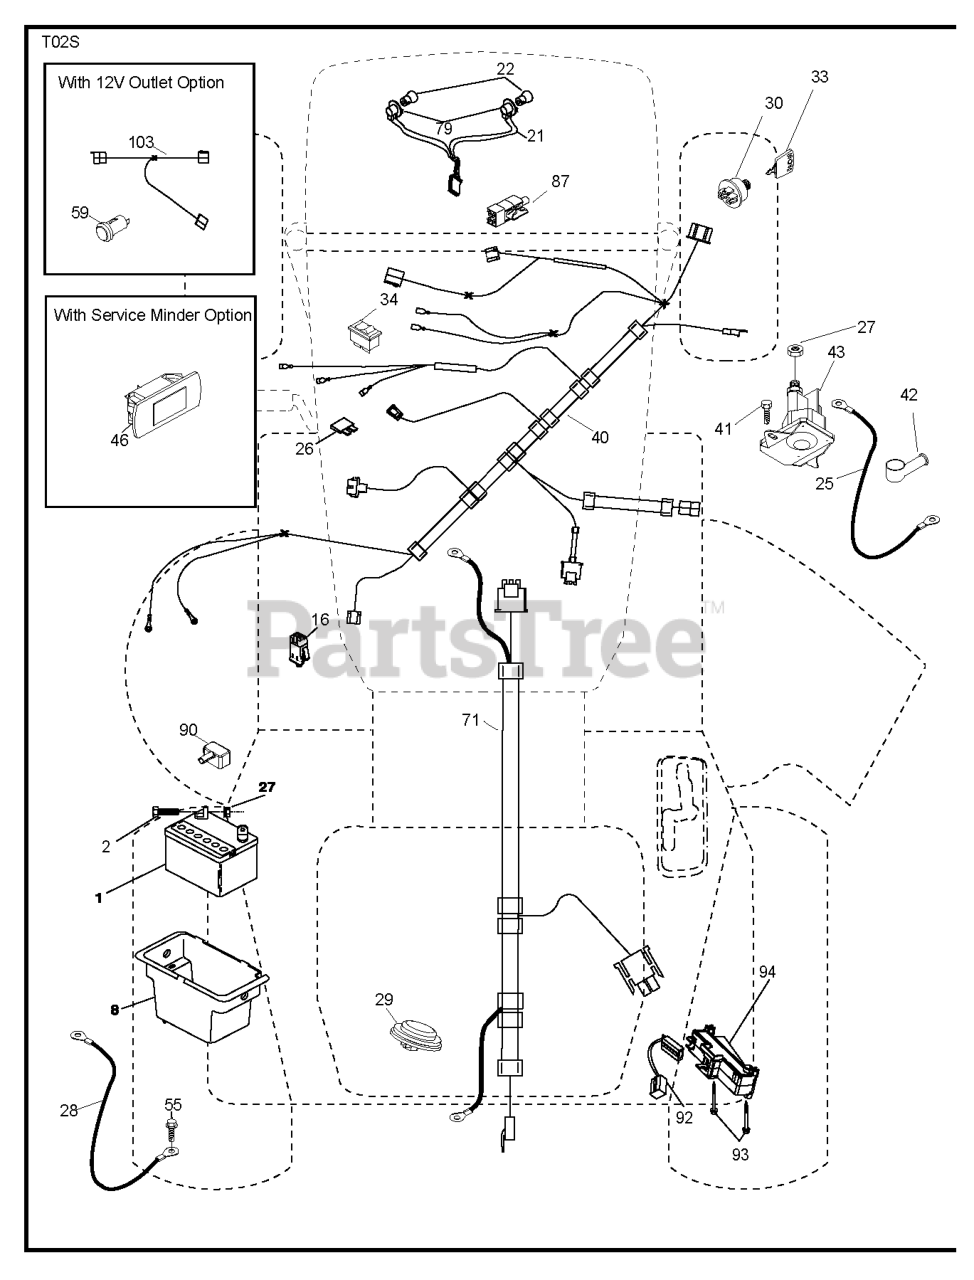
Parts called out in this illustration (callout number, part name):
1	Battery 12 Volt 25 Amp
2	BOLT.HEX.1/4.X.3/4.DICHROMATE
8	BOX.BATTERY.MNT.REAR.L
16	SWITCH INTERLOOK PUSH-IN
21	HARNESS.LIGHT W/4152J BULBS
25	CABLE.STARTER.6GA.BL/RED.14.
26	FUSE 20AMP
27	NUT
28	CABLE.BLACK.18"REAR.BA
29	SWITCH.SEAT.DELTA.OPC.
30	SWITCH.IGN.DELTA.W.LGH.ROS
33	KEY.CHAIN.BLISTER.PACK.GEN.USA
40	HARNESS IGN. DASH
41	SCREW
42	TERMINAL COVER
43	SOLENOID.W/BRASS.PLUNGER
46	RP.GUAGE.SRVCMNDR.HRMTR.
55	SCREW 5/16"
71	HARNESS.IGN.CHASS.TEX.REAR.BAT
79	BULB HOLDER ASM.
87	SWITCH.INTRLCK.CLUTCH.
90	COVER, TERMINAL BATTERY
92	HARNESS.PIGTAIL.CONSLE
93	SCREW.PLASTITE
94	MODULE.REVERSE.ROS
